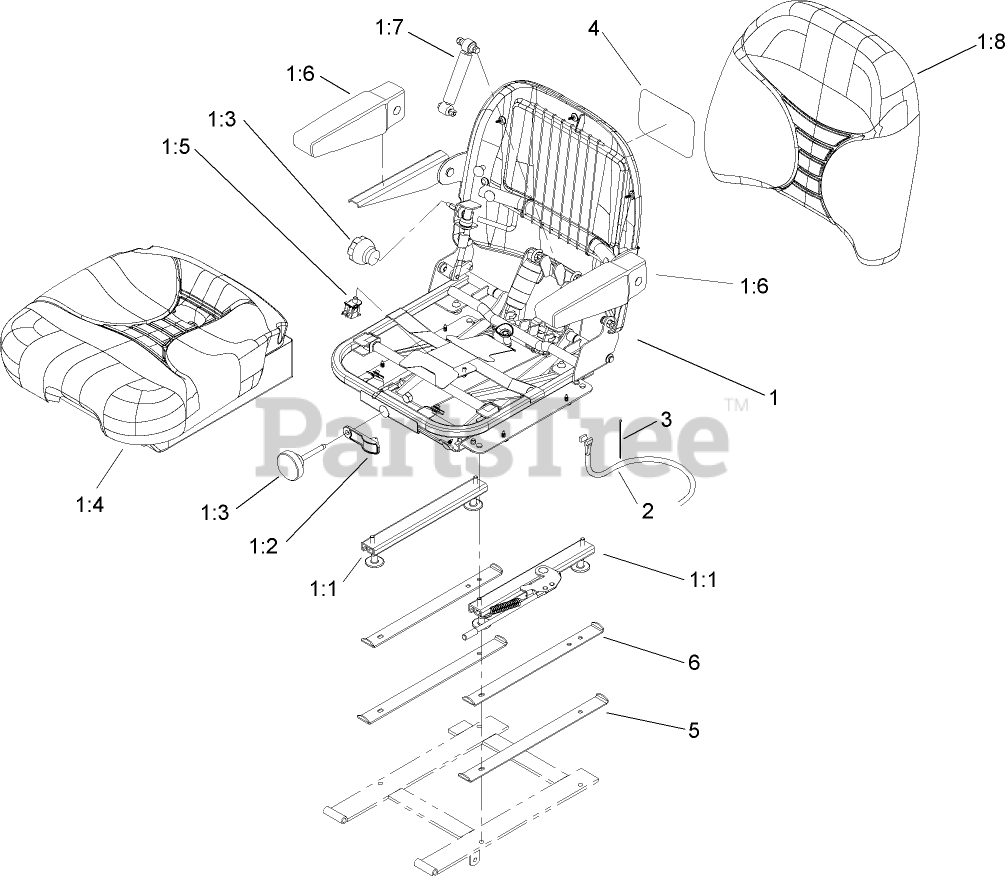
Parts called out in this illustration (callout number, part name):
1	SEAT ASM
1:1	Seat Track Kit
1:2	Weight Indicator Kit
1:3	Knob Kit
1:4	Bottom Cushion Kit
1:5	Switch Kit
1:6	PAD-ARMREST
1:7	Shock Absorber Kit
1:8	Back Cushion Kit
2	HARNESS-WIRING, SEAT
3	TIE-PLASTIC
4	DECAL
5	STOP-SEAT
6	STOP/SPACER-SEAT
